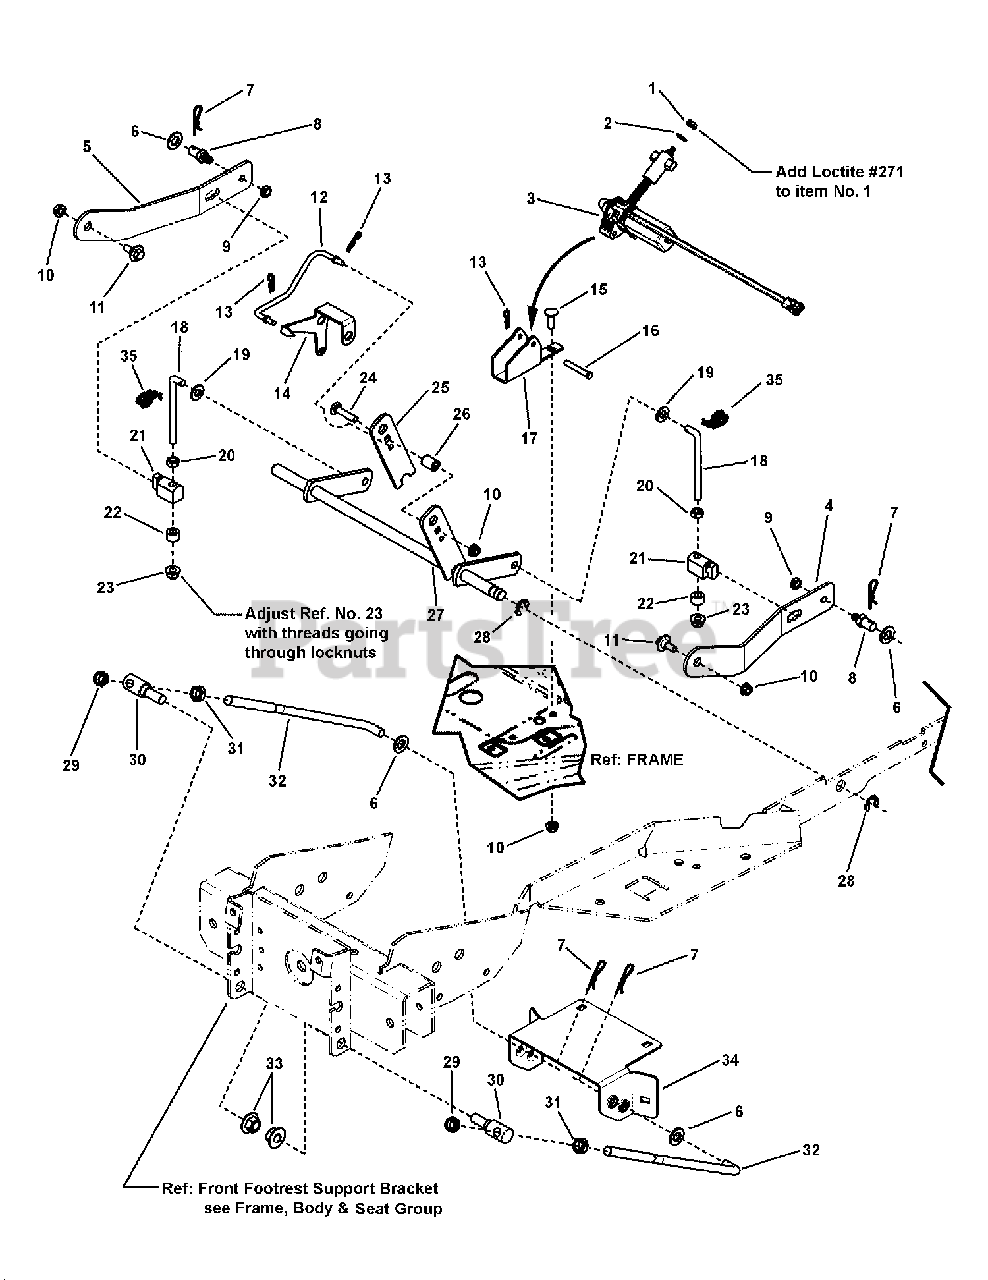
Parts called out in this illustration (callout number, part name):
1	NUT, 1/4-20 Hex, L.H. Thread
2	WASHER, 1/4" Flat (.27 I.D. x .62 O.D.)
3	MOTOR, Linear Actuator (Electric)
4	ARM, Mower Lift L.H.
5	ARM, Mower Lift R.H.
6	WASHER, 1/2" Flat (0.51 I.D. x 1.00 O.D. x .10 Thick)
7	CLIP, Hair Pin .093 Dia.
8	PIN, 3/8-16 Threaded Shoulder
9	NUT, 3/8-16 Hex Center Lock Jam
10	NUT, 5/16-18 Hex Flange Lock, Small - Black
11	SHOULDER BOLT, 5/16-18
12	ROD, Height-of-Cut Indicator
13	HAIR PIN
14	INDICATOR, Height-of-Cut
15	BOLT, Carriage, Short Neck, 5/16-18 x 1
16	PIN, Shear
17	BRACKET, Electric Motor Mount
18	ROD, Mower Lift, 3/8-16 Thread
19	WASHER, .375 Flat (.41 I.D. x .87 O.D.)
20	NUT, HEX 3/8-16 Hex
21	TRUNNION, Powdered Metal
22	SPACER, .385 I.D. x .6697 O.D. x .455 Long (Powdered Metal)
23	NUT, 3/8-16 Hex Flange Nyloc
24	BOLT, 5/16-18 x 1-1/2" Round Head Short Square Neck, GR5
25	ARM, Lift Trunnion
26	SPACER, .328 I.D. x .625 O.D. x .781 Long (Powdered metal)
27	WELDMENT, Lift Shaft
28	RING, External (Klipring) for .625 Dia. Shaft
29	NUT, 1/2-13 Hex Jam
30	TRUNNION, 1/2-13 Thread
31	NUT, 1/2-13 Hex Jam
32	ROD, Front Rail, 52" Mower (1/2-13 Thread)
33	NUT, HEX FLANGE 1/2-13 Hex Flange Two Way Lock
34	HITCH, Front, 52" Mower
35	COTTER PIN, Self Locking, 3/8, YZ
